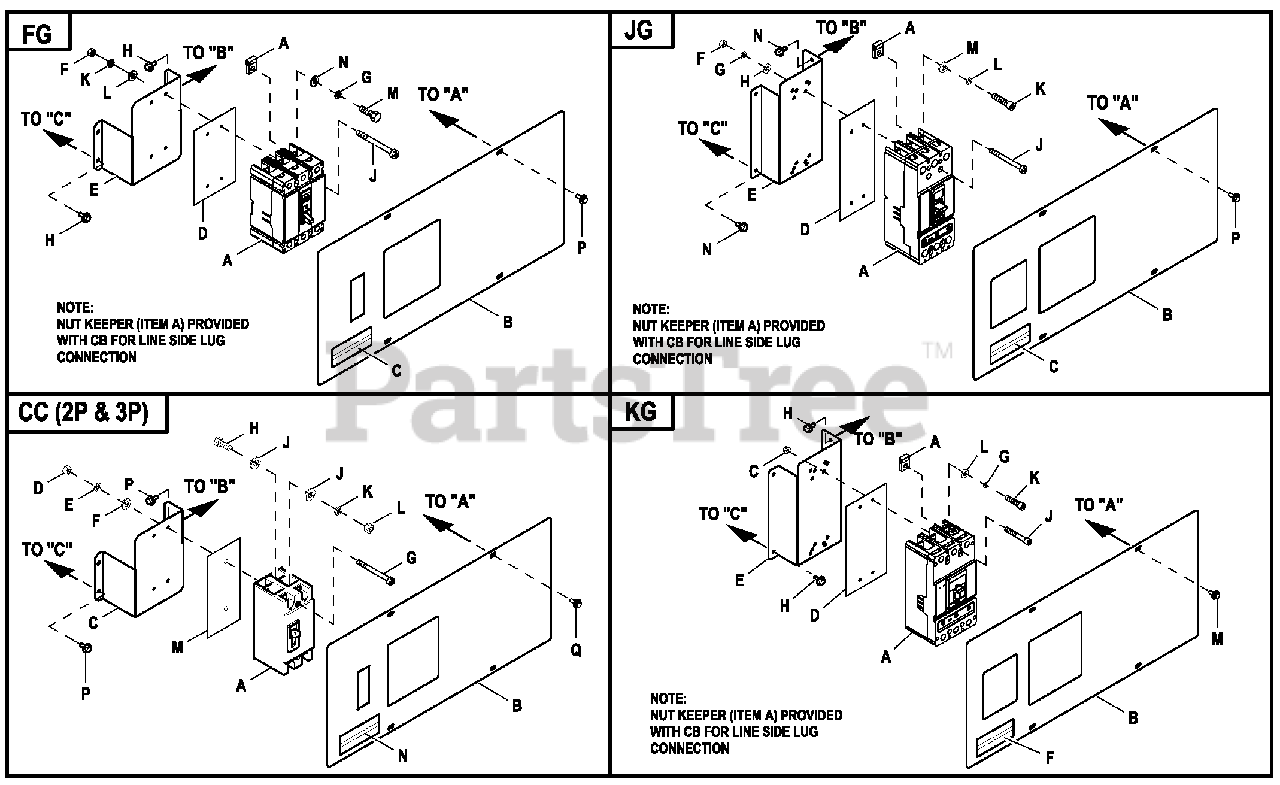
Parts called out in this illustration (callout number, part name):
A	CB 0060 3P 480V E FG LL
B	CONBOX CONTRL COVER PNL
C	DECAL TERMINAL SHOCK HZD BI
D	INSULATOR CB 3P E TYPE CC/FG
E	STANDOFF CB BOX CONBOX
F	NUT HEX #8-32 STEEL
G	WASHER LOCK M5
H	SCREW HWHTF M6-1.0X 16
J	SCREW PPHM #8-32 X 1-3/4 ZINC
K	WASHER LOCK #8-M4
L	WASHER FLAT #8 ZINC
M	SCREW PPHMM5-0.8X12ZNC
N	WASHER FLAT #10 ZINC
P	SCREW HWHT M6-1 X 16 N WA Z/JS
A	CB 0250 3P 600V E JG LL
B	COVER PLATE CNTRL PNL JG KG 3P
D	INSULATOR CB E 3P JG
E	STANDOFF CB C2 ET KG JG
F	NUT HEX 1/4-20 STEEL
G	WASHER LOCK M6-1/4
H	WASHER FLAT 1/4-M6 ZINC
J	SCREW RHM 1/4-20X3
K	SCREW SHC M8-1.25 X 20 G8
L	WASHER LOCK M8-5/16
M	WASHER FLAT 5/16-M8ZINC
N	SCREW HWHTF M6-1.0X 16
A	CB 0125 3P 240V ECC LL
B	COVER PLATE CNTRL PNL CC
C	STANDOFF CB BOX CONBOX
D	NUT HEX #8-32 STEEL
E	WASHER LOCK #8-M4
F	WASHER FLAT #8 ZINC
G	SCREW RHM #8-32X3-1/4
H	SCREW HHC M6-1.0X20 C8.8
J	WASHER FLAT 1/4-M6 ZINC
K	WASHER LOCK M6-1/4
L	NUT HEX M6-1.0 G8 CLEAR ZINC
M	INSULATOR CB 2P E TYPE CC
N	DECAL TERMINAL SHOCK HZD BI
P	SCREW HWHTF M6-1.0X 16
Q	SCREW HWHT M6-1 X 16 N WA Z/JS
